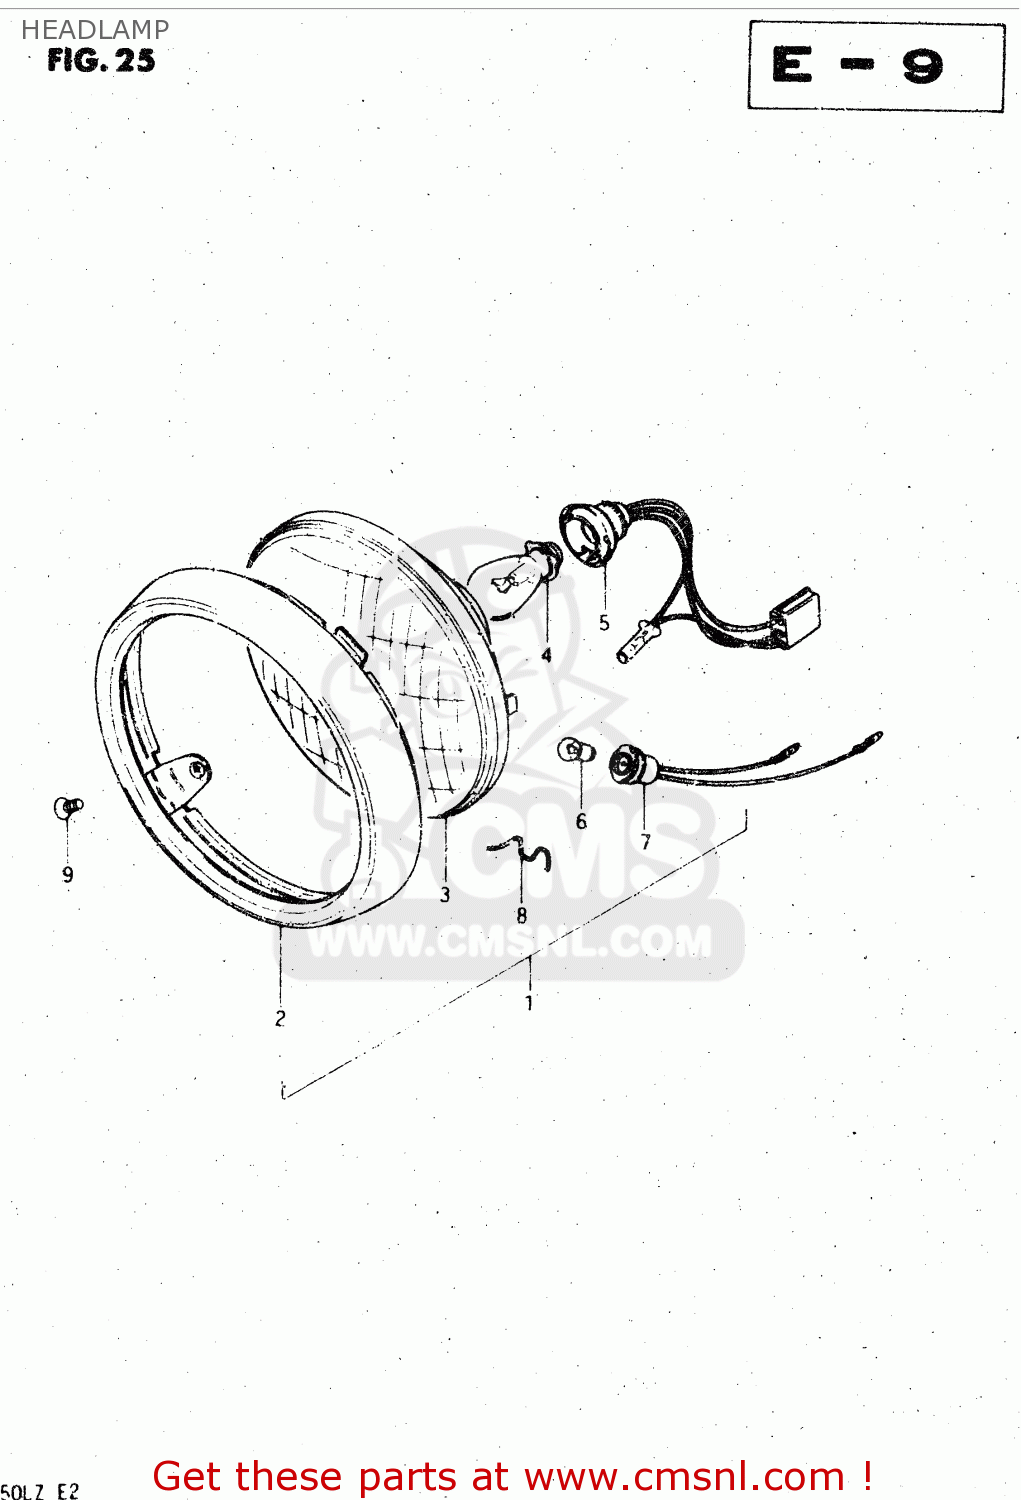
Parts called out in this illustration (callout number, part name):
1	HEADLAMP ASSY
2	RIM
3	LAMP UNIT
4	BULB
5	SOCKET
6	BULB(12V3.4W,STANLEY,A72A)
7	SOCKET
8	SPRING
9	SCREW(5X12)
